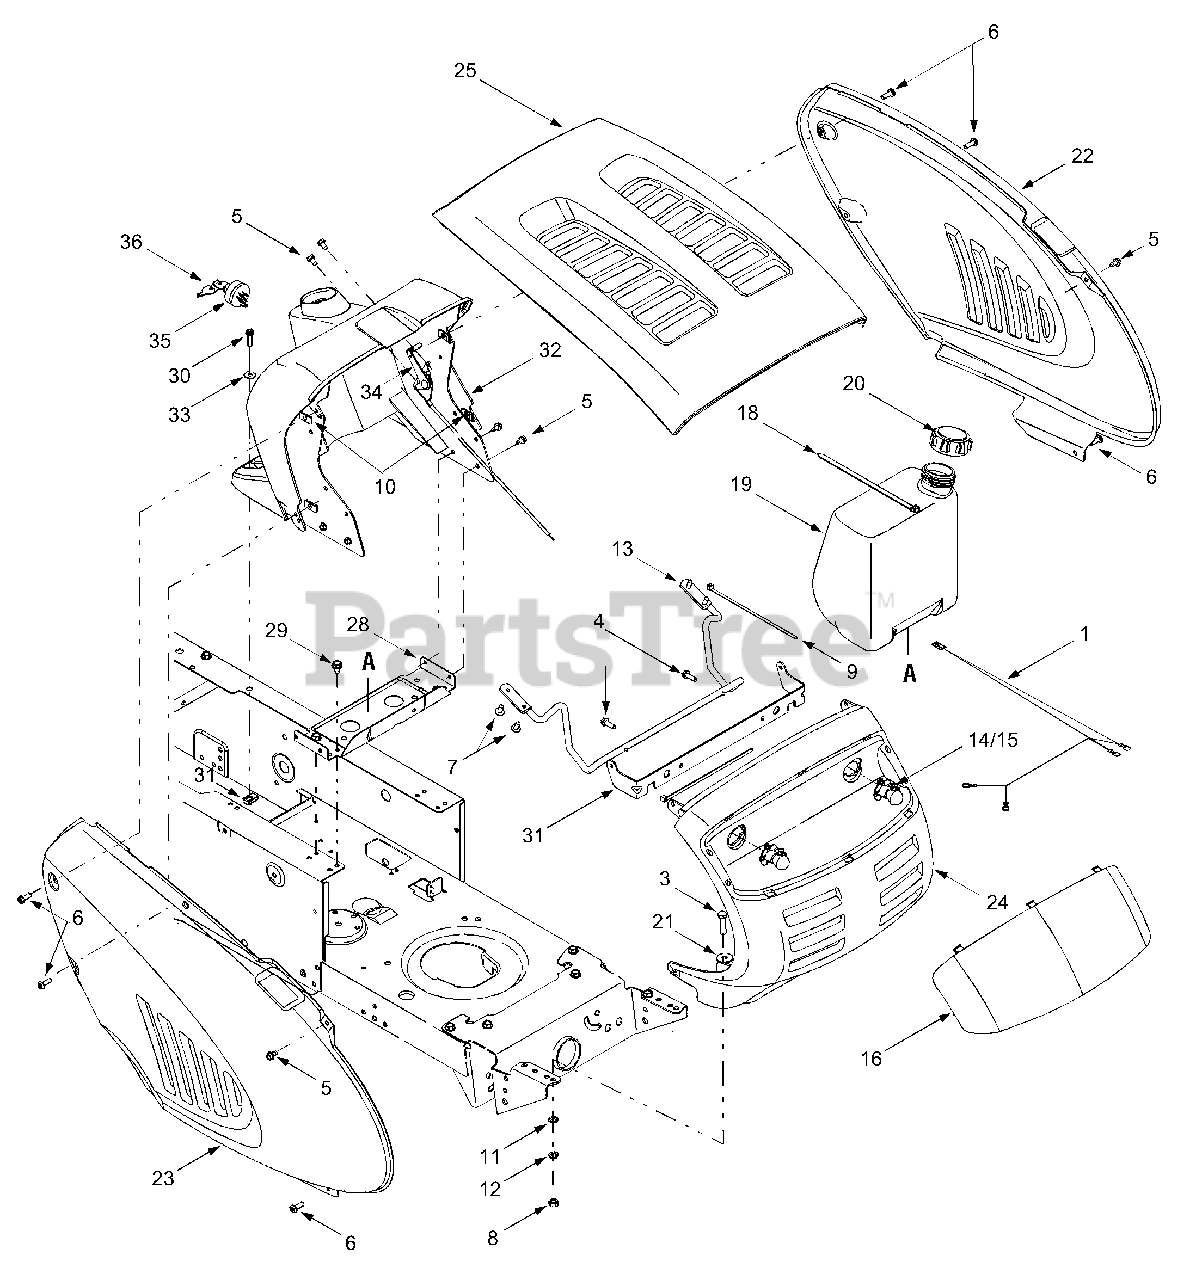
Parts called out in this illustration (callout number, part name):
1	Headlamp Harness Assembly
3	Hex Screw, 5/16-18 x 1.50
4	Self-tapping Screw, 1/4-15 x .75
5	Self-tapping Screw, 1/4-20 x .5
6	Machine Screw, 1/4-20 x .75
7	Screw, 1/4-20 x .625
8	Hex Nut, 5/16-18
9	Cable Tie, 7.4"
10	U-type Speed Nut
11	Speed Nut, 5/16
12	Lock Washer, 5/16
13	Hinge Rod
14	Headlamp, 12V
15	Headlamp Socket
16	Headlight Lens
17	Rubber Washer, .87 x .33
18	Cable Tie, 30.66
19	Fuel Tank, 1.5 gal.
20	Fuel Tank Cap
21	Flat Washer, .344 x 1.0 x .063
28	Battery Support Bracket
29	Self-tapping Screw, 5/16-18 x .5
30	Self-tapping Screw, 1/4-20 x 1.0
32	Dash Panel
33	Flat Washer, .260 x .720 x .060
34	Throttle / Choke Control, 18.5"
35	Ignition Switch, 6-pin
36	Keys (pair)
